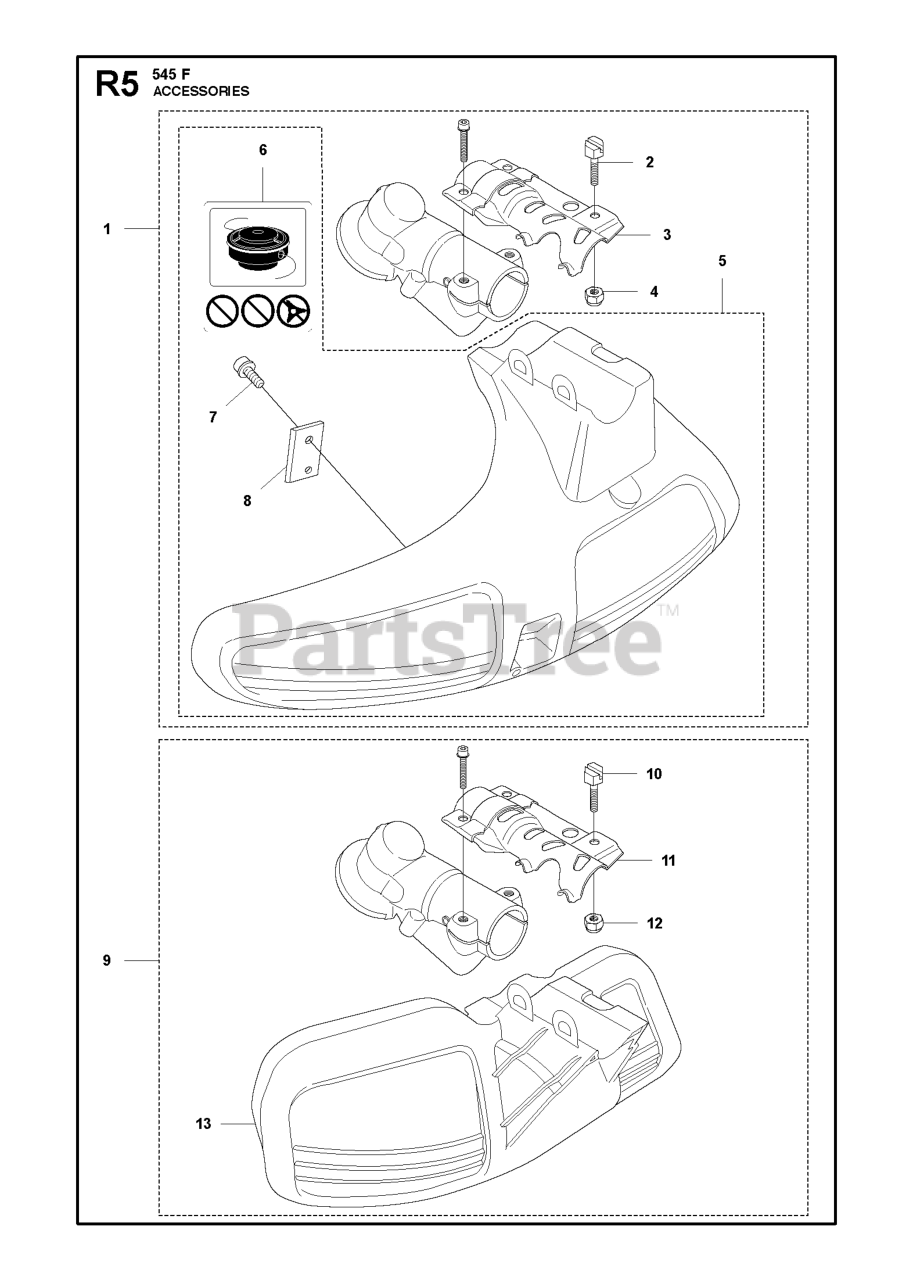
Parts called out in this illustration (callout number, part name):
1	TRIMMER GUARD ASSY
4	LOCKNUT M6
9	TRIMMER GUARD COMPL
12	LOCKNUT M6
13	BLADE GUARD
